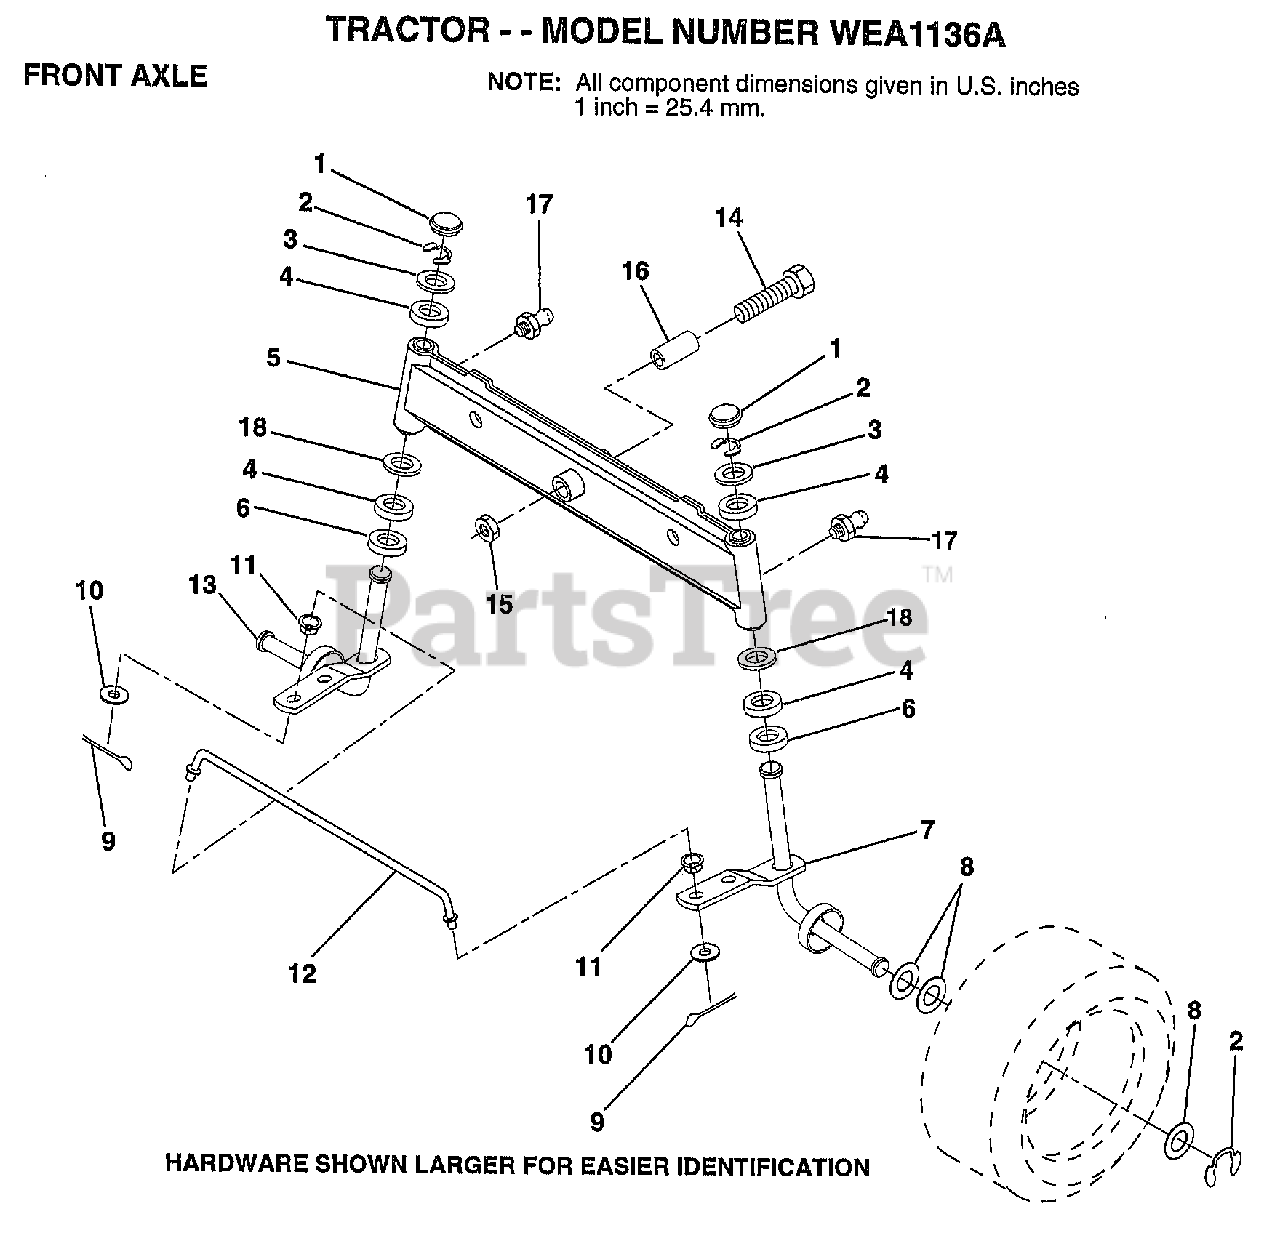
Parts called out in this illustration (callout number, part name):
1	CAP
2	RING
3	WASHER
4	COL. SRTG. BEAR.
5	AXLE ASM FRONT
6	WASHER .T
7	SPINDLE.ASSY.RH
9	COTTER PIN
10	WASHER
11	BUSHING.DRAGLINK
12	TIE ROD
13	SPINDLE.ASSY.LH
14	BOLT HEX 5/8-11
15	"NUT-LOC,FLANGE LT"
16	BEARING
17	ZERK M
18	WASHER
